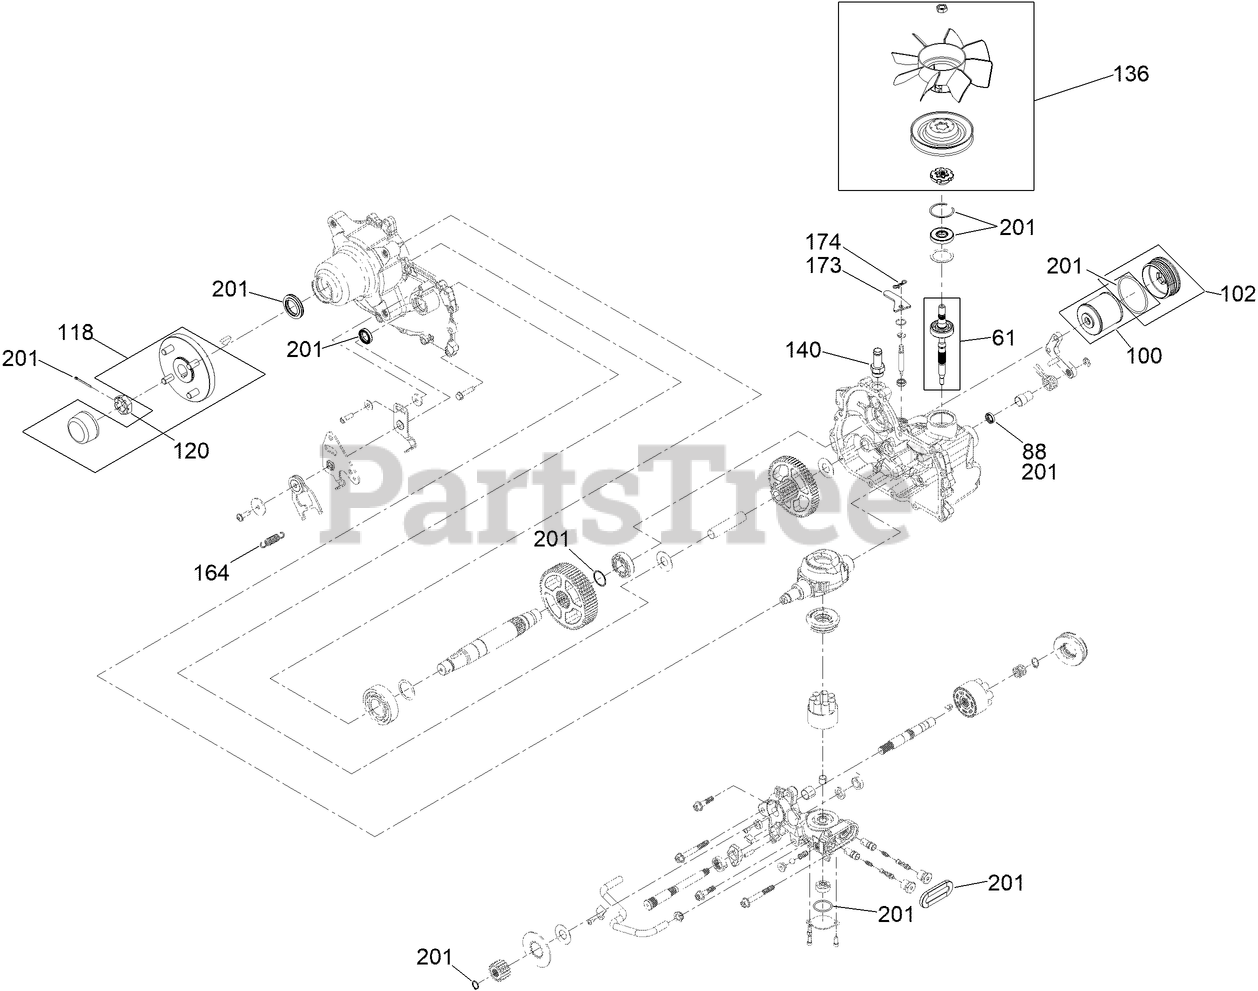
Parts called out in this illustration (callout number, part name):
61	KIT, INPUT SHAFT
88	SEAL, BRAKE
100	KIT, FILTER
102	KIT, FILLER CAP
118	HUB-4 BOLT
120	NUT, SLOTTED
136	KIT, FAN AND PULLEY
140	FITTING-5/8 BEADED, 7/8 SAE
164	SPRING-EXTENSION
173	PLATE-LEVER, BYPASS
174	PIN-COTTER, LOCKING
201	KIT, SEAL
